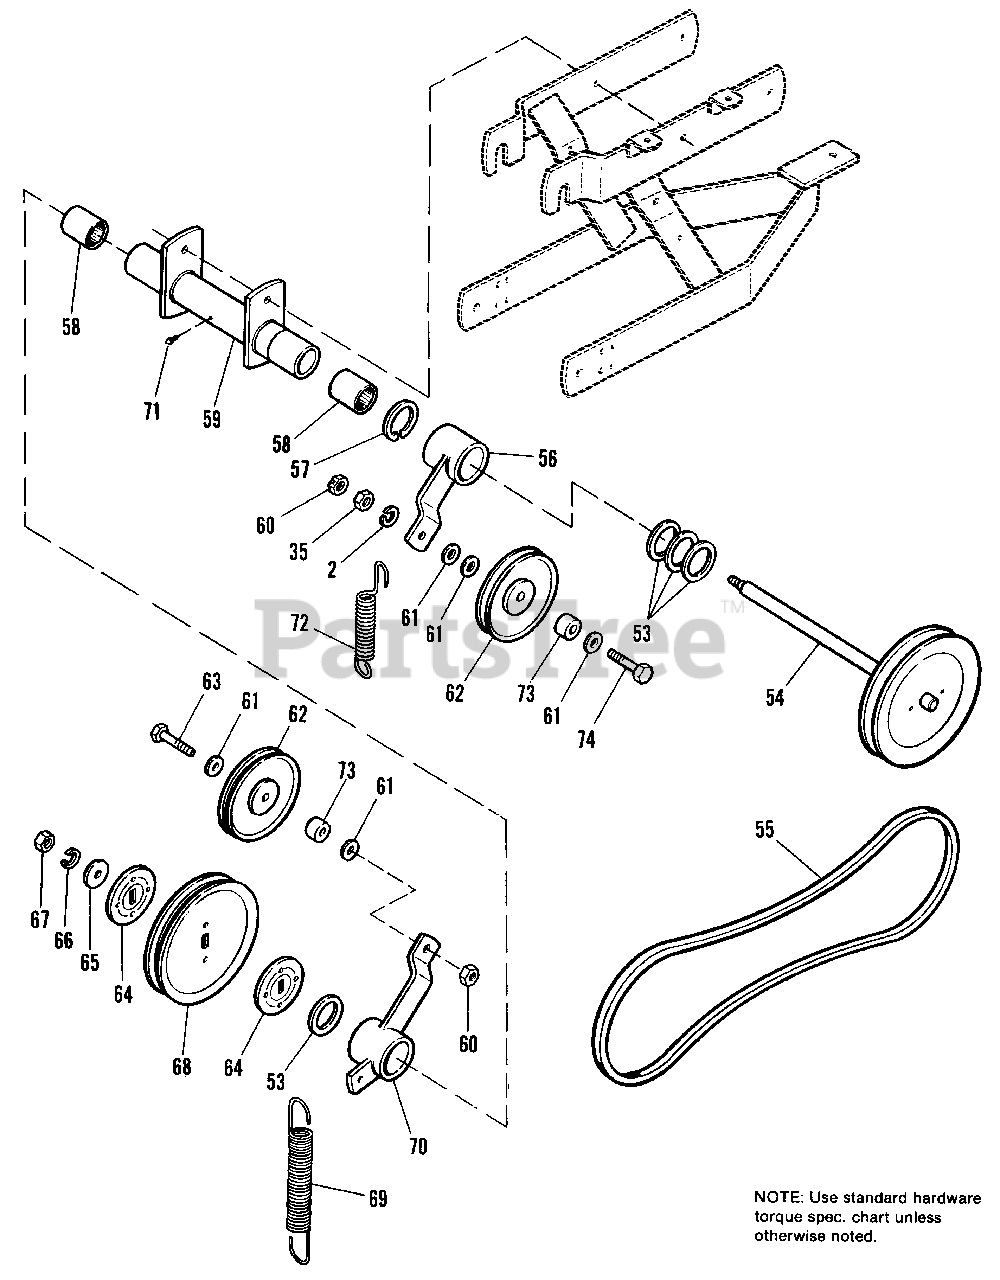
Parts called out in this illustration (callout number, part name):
54	SHAFT ASSY.
55	V-BELT
56	ARM ASSY., Tension
57	RING, Retaining
58	BEARING, Needle
59	HOUSING ASSY., Bearing (Incl. Ref. No. 58, Qty. 2)
60	LOCKNUT, Hex, 3/8-16
61	WASHER, Plain, 3/8
62	PULLEY ASSY., Idler
63	CAPSCREW, Hex Hd., 3/8-16 x 1-1/2
64	WASHER, Special
65	WASHER, Plain, 7/16
66	LOCKWASHER, 7/16
67	NUT, Hex, Full, 7/16-14
69	SPRING, Tension
70	ARM ASSY., Idler
71	FITTING, Grease
74	CAPSCREW, Hex Hd., 3/8-16 x 2
